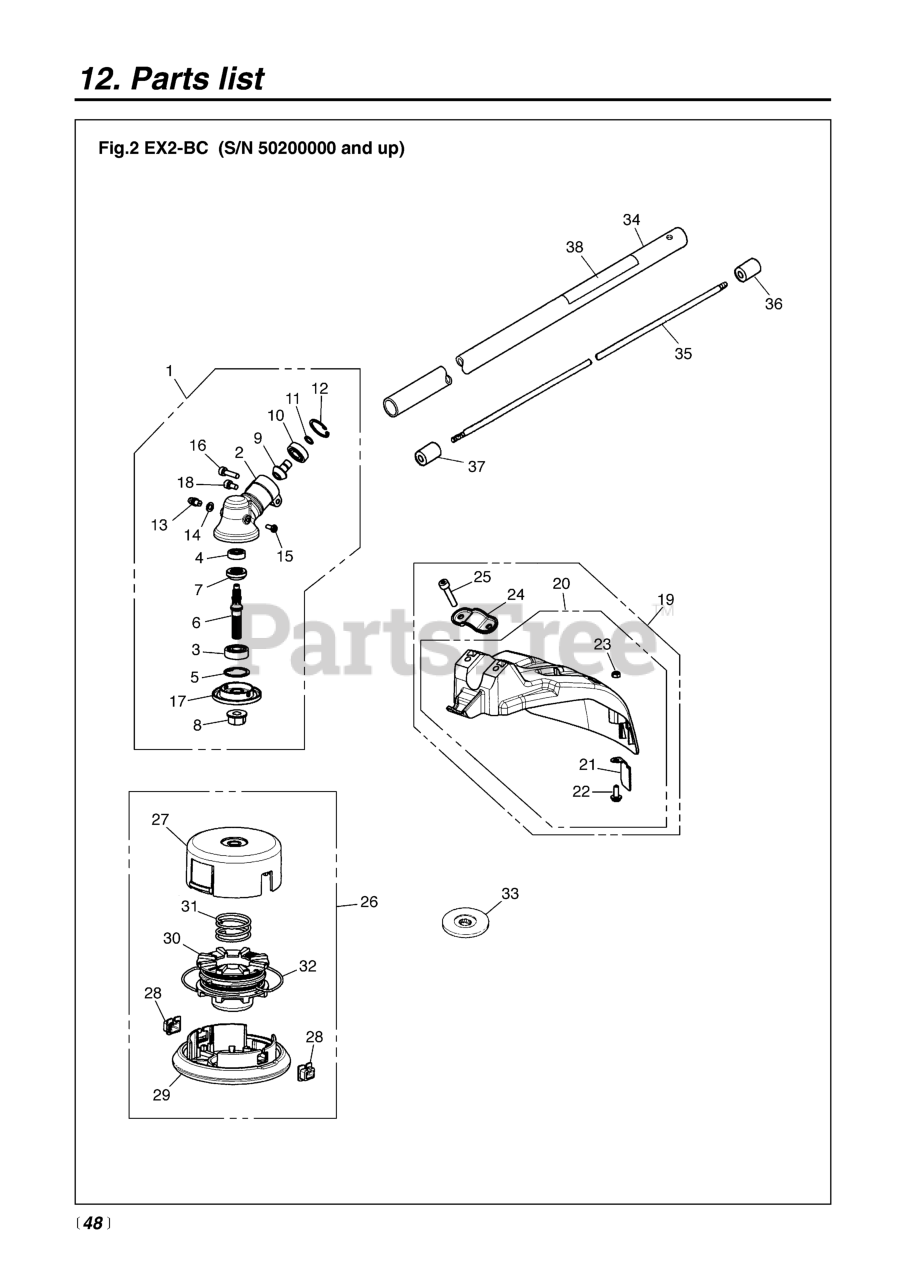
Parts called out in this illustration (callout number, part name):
1	GEARCASE ASSY.
2	GEARCASE
3	BEARING
4	BEARING (RPLS T3300-13521)
5	RING, SNAP, M26 X 1.2
6	SHAFT
7	GEAR
8	NUT
9	PINION
10	BEARING (RPLS T3300-13531)
11	RING, SNAP (RPLS T3300-13330)
12	RING, SNAP, M24 x 1.2
13	FITTING, GREASE
14	WASHER, M6 X .8
16	BOLT (RPLS 2850-14220)
17	HOLDER (A)
18	BOLT
19	GUARD ASSY. (RPLS -24002)
20	GUARD COMP.
21	BLADE (RPLS T3002-24120)
22	SCREW TORX
23	NUT
24	CLAMP (REPLACES 5807-24120)
25	BOLT, TORX
26	TAP HEAD COMP.
27	CASE (REPLACES -15111)
28	EYELET
29	COVER (REPLACES -15131)
30	HOLDER, CORD (REPLACES-15141)
31	SPRING
32	CORD
33	HOLDER (B)
34	PIPE COMPLETE
35	SHAFT
36	JOINT, SHAFT (RPLS -12240)
37	SPACER
38	PLATE, NAME
